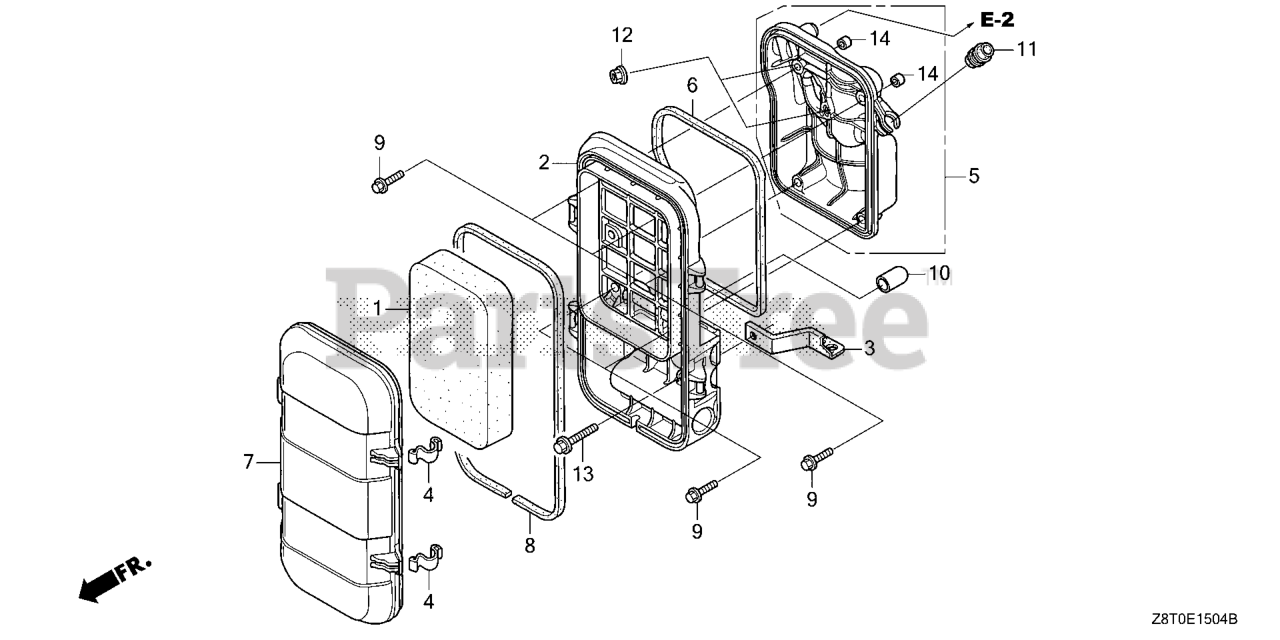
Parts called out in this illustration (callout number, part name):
1	ELEMENT, AIR CLEANER
2	HOUSING, AIR CLEANER
3	STAY, AIR CLEANER
4	SPRING, AIR CLEANER HOUSING LID
5	BASE, AIR CLEANER
6	SEAL, AIR CLEANER HOUSING
7	COVER, AIR CLEANER
8	SEAL, AIR CLEANER COVER
9	BOLT, FLANGE (5X18)
10	CAP, SEALING
11	RUBBER, FUEL (9X15X20)
12	NUT, FLANGE (6MM)
13	BOLT, FLANGE (6X32)
14	COLLAR, AIR CLEANER
